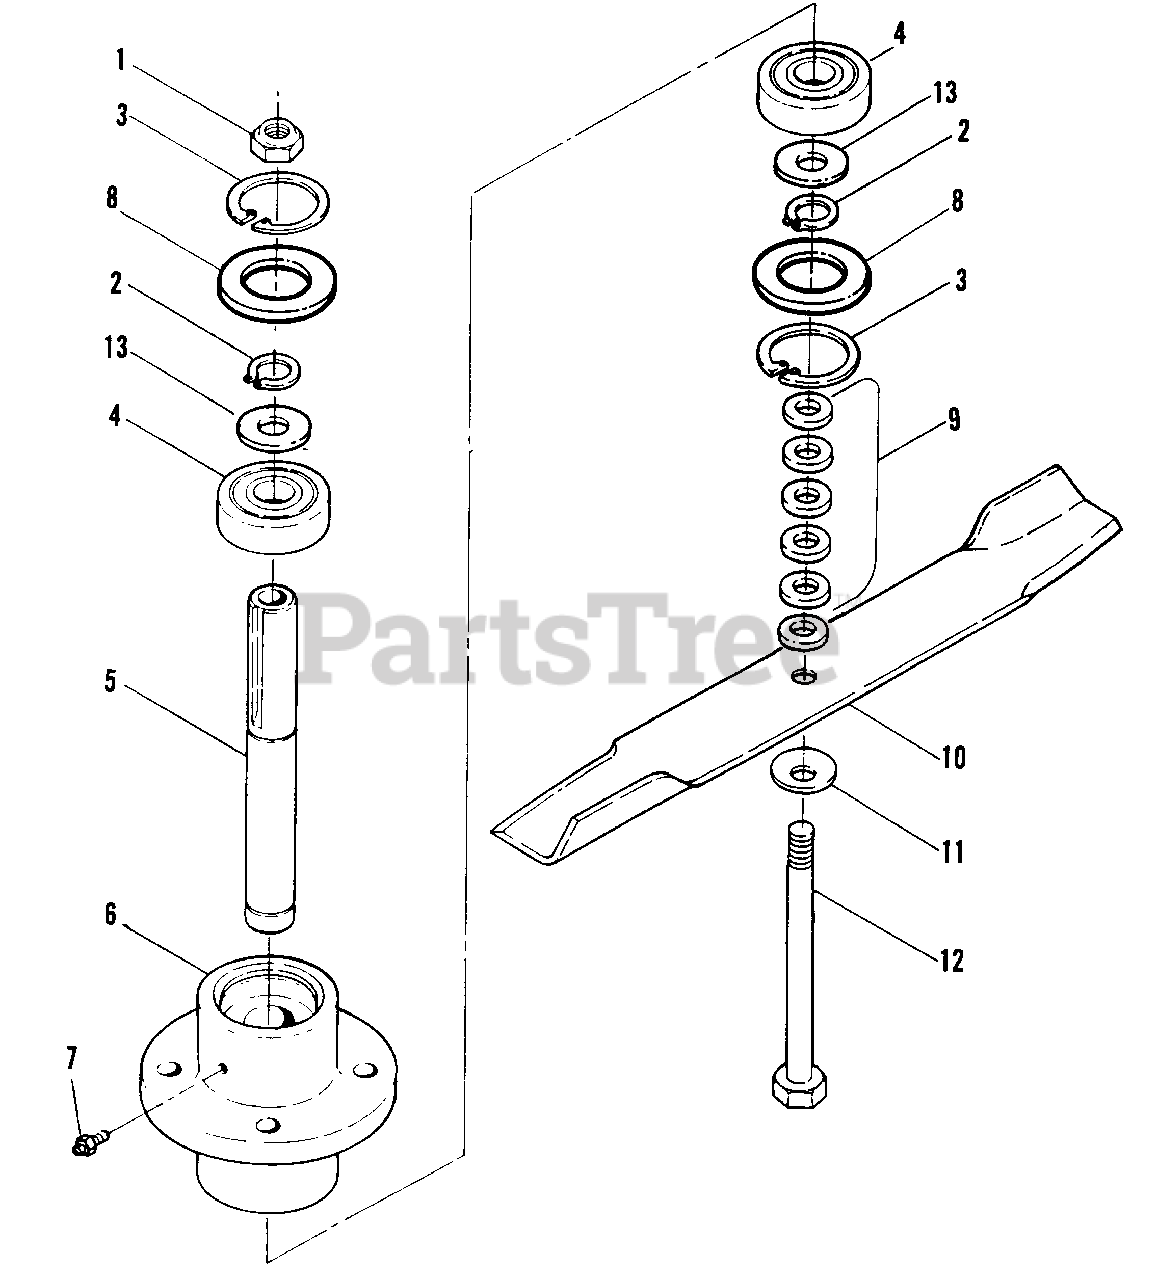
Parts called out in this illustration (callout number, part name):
1	NUT, 5/8" F Hex
2	SNAP RING
3	SNAP RING
4	BEARING, Sealed
5	SHAFT, Spindle
6	HOUSING, Cutter
7	FITTING, 1/8" NPT Zerk
8	WASHER, Spindle Housing
9	SPACER, Blade
10	BLADE, 18" High Lift
11	WASHER, 5/8" Bevel
12	SCREW, 5/8-18 x 9-3/4" Hex Cap
13	WASHER, Spindle
